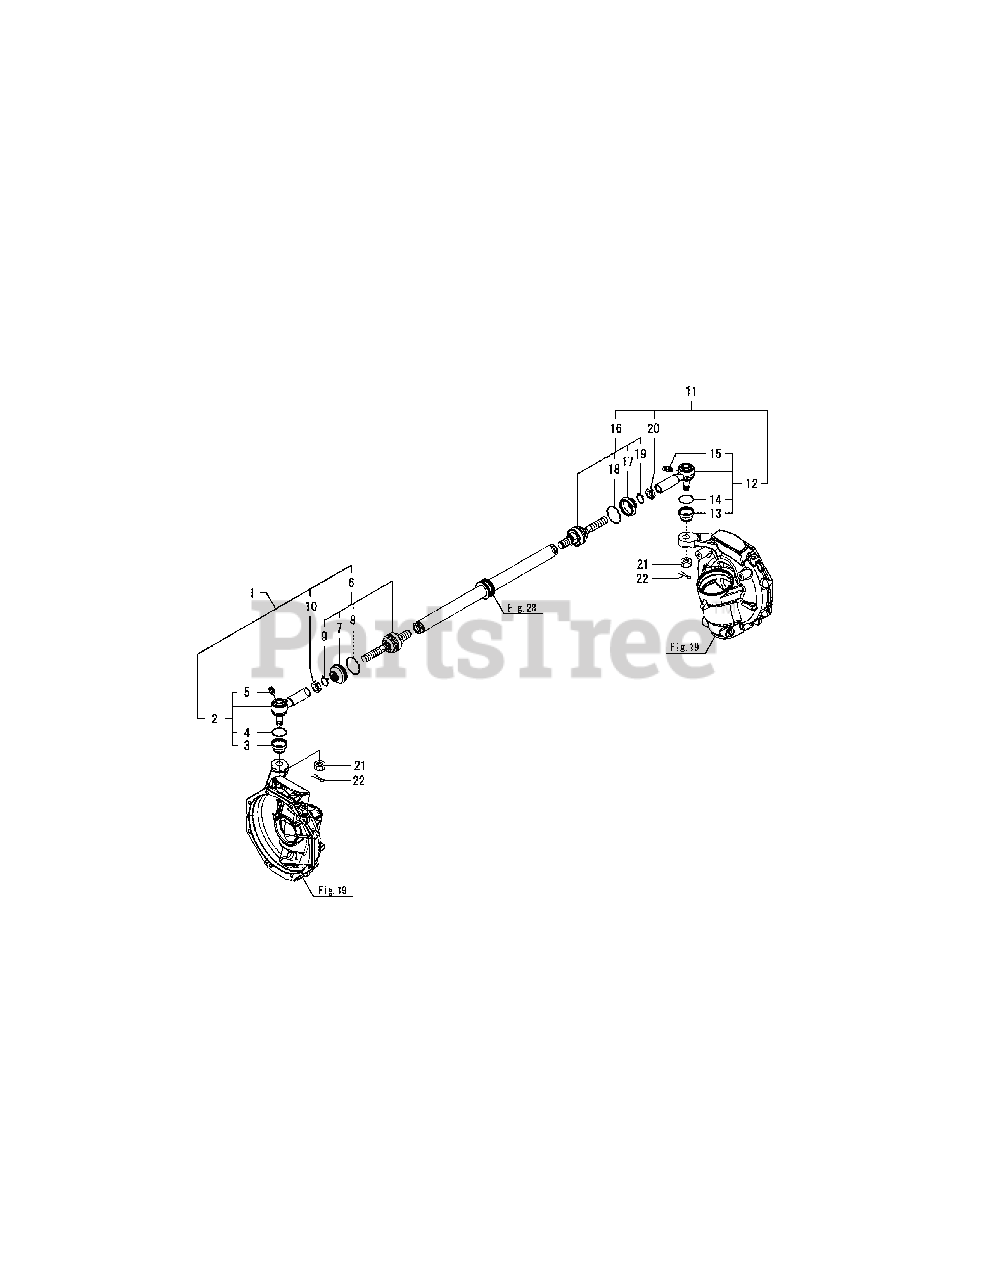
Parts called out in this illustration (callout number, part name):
1	TIE-ROD ASSY, LEFT
2	END ASSY, ROD L
5	GREASE NIPPLES
6	END ASSY, RACK L
11	TIE-ROD ASSY, RIGHT
12	END ASSY, ROD R
15	GREASE NIPPLES
16	END ASSY, RACK R
22	COTTER PIN 4.0X40
